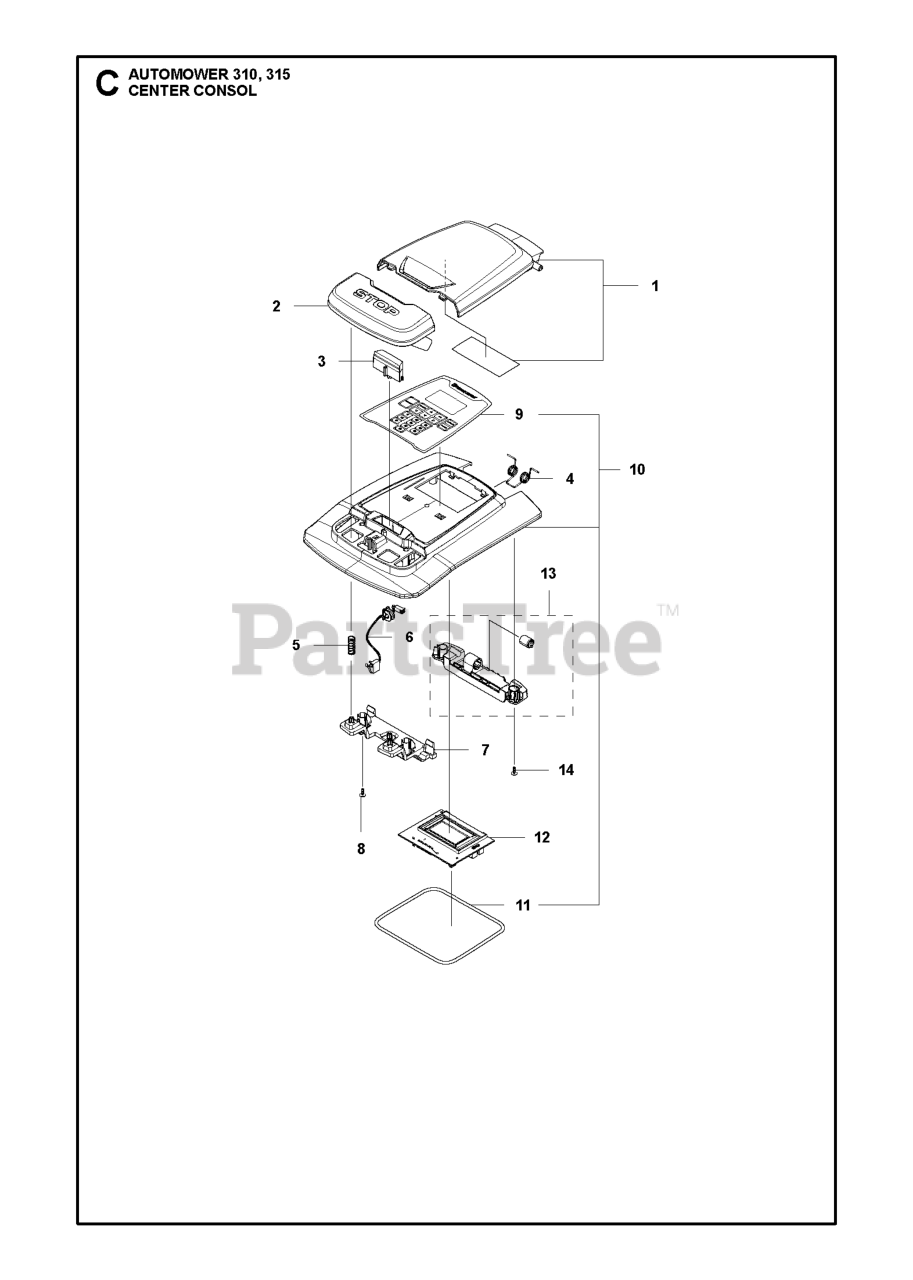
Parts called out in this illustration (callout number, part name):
1	HATCH KIT
2	BUTTON STOP
3	LOCK
4	TORSION SPRING DT=1,3MM
5	SPRING LOCK STOP BUTTON
6	SWITCH STOP BUTTON NO ANCHOR
7	SUPPORT REAR
8	SCREW 14MM
9	KEYBOARD 2.8" DISPLAY
10	COVER KIT 2.8" DISPLAY
11	SEALING STRIP P15 UPPER
12	PRINTED CIRCUIT ASSY HMI BOARD
13	SUPPORT KIT
14	SCREW 14MM
